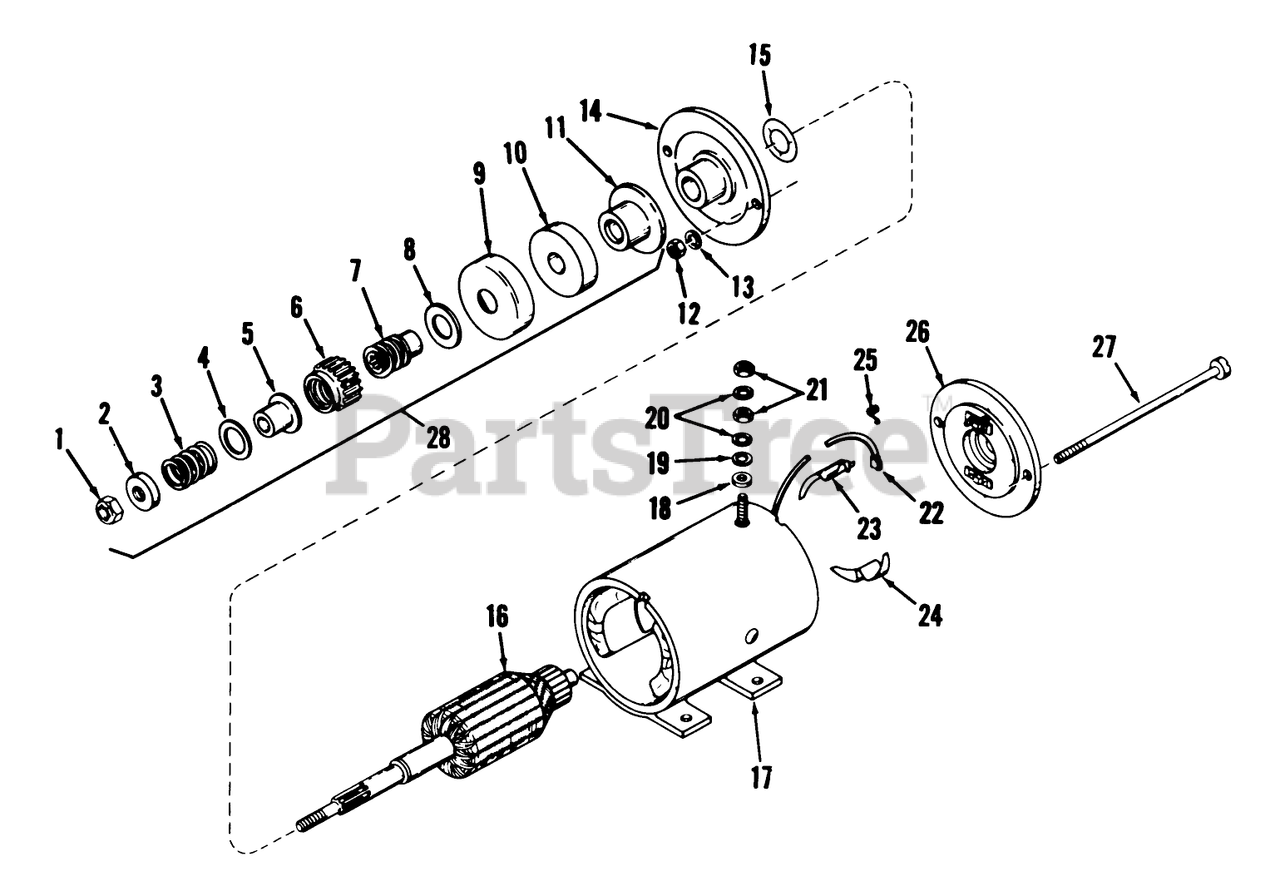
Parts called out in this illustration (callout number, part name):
1	Nut, Elastic stop
2	51084 3 1/2HP W/334
3	Spring, Anti-drift
4	Washer, Pinion
5	Sleeve, Anti-drift
6	Gear, Pinion
7	Shaft, Screw
8	Washer, Thrust
9	Cup, Cushion
10	Cushion, Rubber
11	Washer, Thrust
12	Nut, Securing
13	Washer, Lock
14	Cap Assy., Drive end (Incl. bearing)
15	Washer, Spacing (.010 thick)(Use as required)
15	Washer, Spacing (.02 thick)(Use as required)
16	Armature
17	Hour Any (Incl. pole shoes, field coils, terminal post, straight mounting bracket, Nos. 18 thru 21, 23, 24, 1 or 22)
18	Washer, Insulating
19	Washer, Plain
20	Washer, Lock
21	61710/VAR.HILLER AT
22	Brush Spring Kit (Incl. No. 25)
23	Insulation
24	Insulation
25	Spring, Brush
26	End Cap Assy., Commutator (Incl. Nos. 25 1 of No. 22)
27	Bolt, Thru
28	Drive Assy., Complete (Incl. Nos. 1 thru 11)
